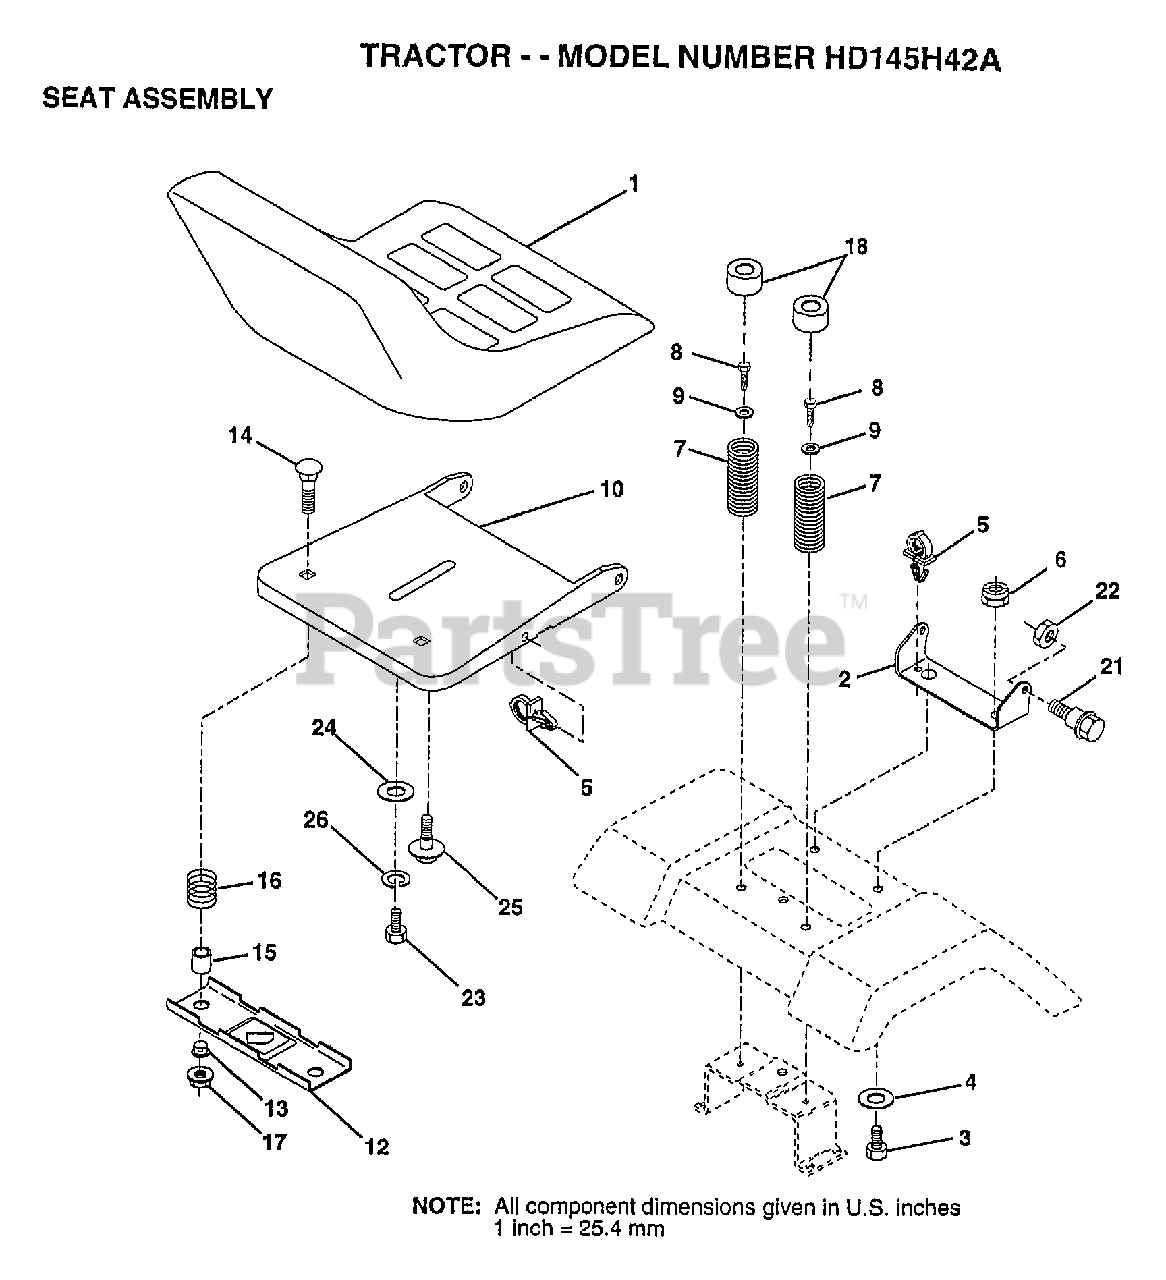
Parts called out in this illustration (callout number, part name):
1	SEAT
2	BRACKET PVT SEAT
3	BOLT
4	WASHER PM
5	CLIP.PUSH-IN.HING
6	NUT
7	SPRING COMPRESSIO
8	SCREW GTV
9	WASHER
10	PAN-SEAT
12	BRKT SWITCH
13	BUSHING
15	SPLIT SPACER
16	SPRING
18	CAP SPRING
21	"BOLT,SHOULDER"
23	BOLT
24	WASHER
25	"BOLT,SHOULDER"
26	LOCKWASHER
